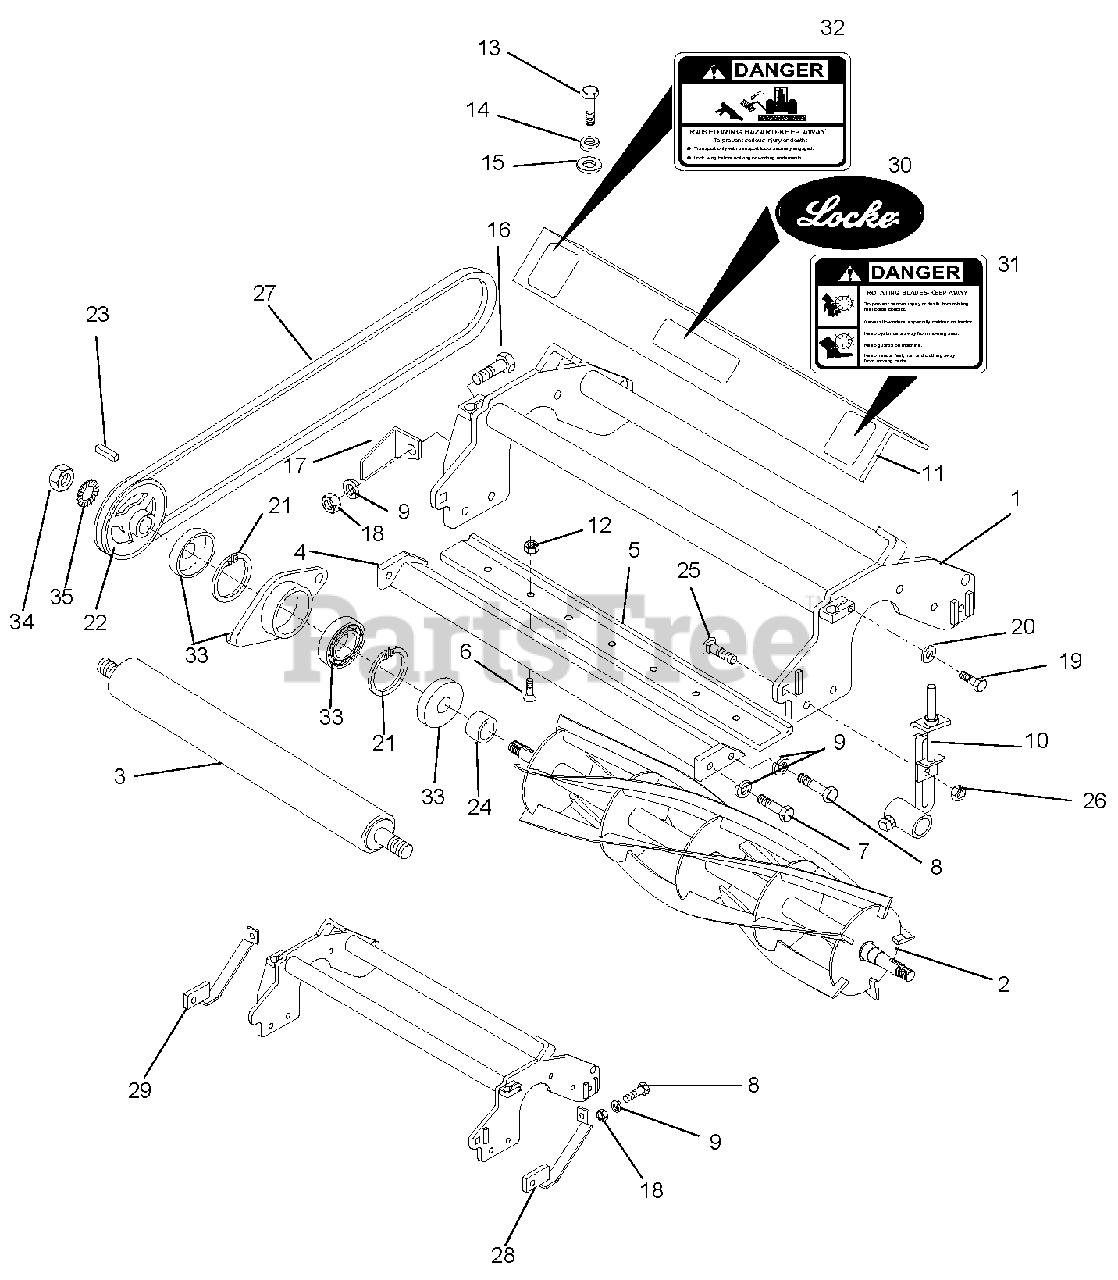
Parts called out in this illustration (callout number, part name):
1	Weldment, Reel Frame Unit 1
2	Reel, 4 Blade
3	Roller Assembly, Smooth Aluminum 3-Inch
4	Weldment, Bed Bar
5	Bedknife
6	Cap Screw, Hex Socket Flat Head .312 x 1
7	Cap Screw, Hex Head .437-14 x 1
8	Cap Screw, Hex Head .437-14 x 1.25
9	Washer, Lock .437
10	Bracket Assembly, Roller Left Hand
11	Shield Assembly Unit 1
12	Nut, Hex Nylock .312-18
13	Cap Screw, Hex Head .312 x .75
14	Washer, Lock .312
15	Washer, Flat .312
16	Cap Screw, Hex Head .437-14 x 1.25
17	Scraper, Pulley Right Hand, Units 1 & 2
18	Nut, Hex .437
19	Cap Screw, Hex Head .375-16 x 1
20	Washer, Lock .375
21	Ring, Retaining 2.50
22	SHEAVE, 7/8 BORE X 4.40 PD
23	Key, Square .25 x .25 x 1
24	Spacer, Drive Side
25	Bolt, Carriage .50-13 x 1.50
26	Nut, Hex Nylock .50-13
27	V-Belt B64
28	Weldment, Skid Shoe Right Hand
29	Weldment, Skid Shoe Left Hand
30	Decal, Legendary Locke Reels
31	Decal, Danger
32	Decal, Danger
33	See Reel Housing Bearing Flange – Non-Drive Side on page 35.
34	Nut, Jam .750 CP NF
35	Washer, Star .75 External Tooth
